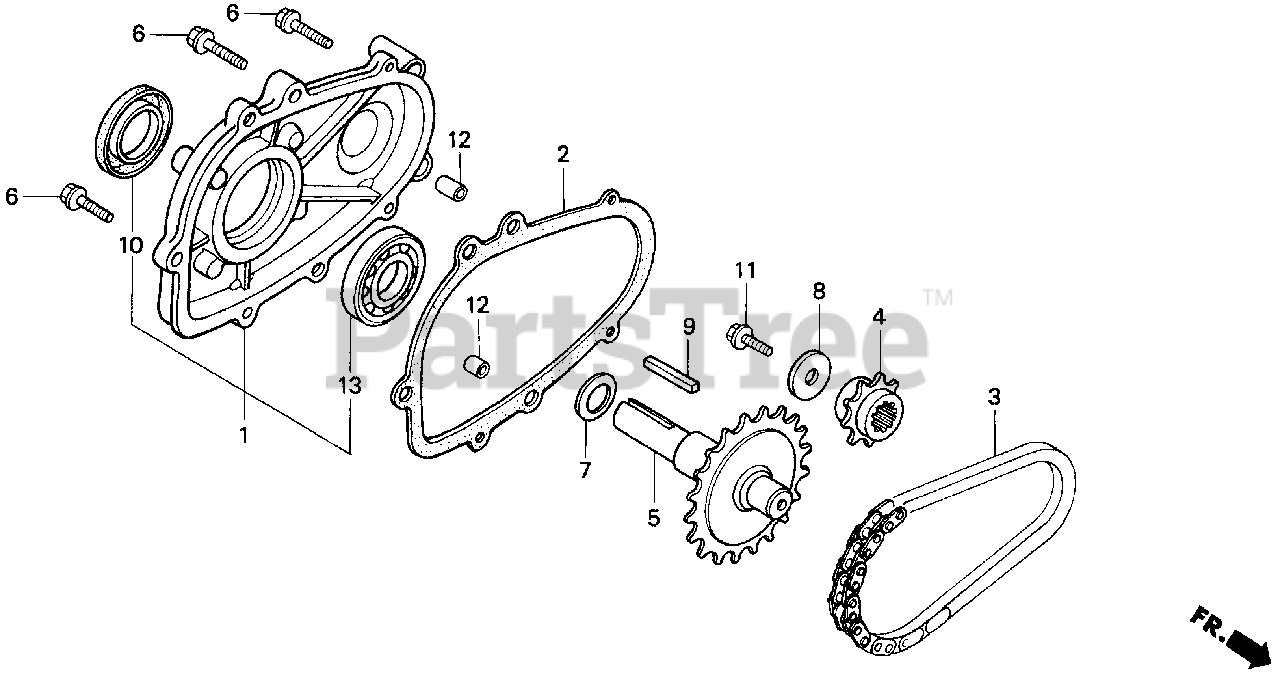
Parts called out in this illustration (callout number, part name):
1	COVER ASSY., CHAIN CASE
2	GASKET, CHAIN CASE COVER
3	CHAIN, P.T.O. DRIVE
4	SPROCKET, DRIVE
5	SHAFT, P.T.O.
6	BOLT, FLANGE (6X28)
7	SPRING, THRUST
8	WASHER (8MM)
9	KEY (5X5X33)
10	OIL SEAL (25X41X6)
11	BOLT, HEX. (8X25)
12	PIN A, DOWEL (8X14)
13	BEARING, RADIAL BALL (6205)
